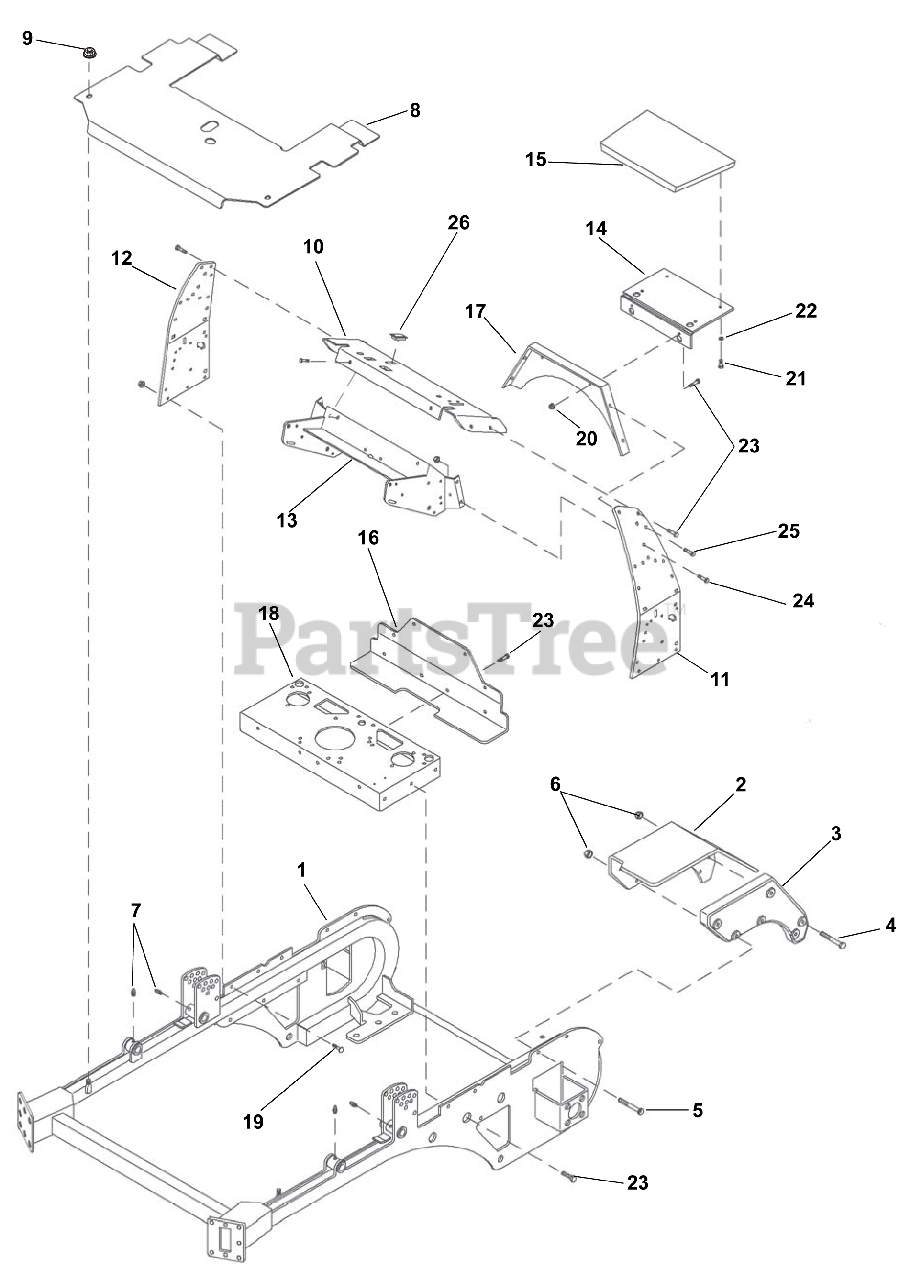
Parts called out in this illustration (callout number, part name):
1	FRAME, W/ 48"-52" DECK
2	FENDER, LEFT
3	WEIGHT
4	BLT-HEX M8-1.25X65 YWZC
5	BLT, HEX M8-1.25X70 YWZC
6	@NUT-LK-NYL M8-1.25 YWZC
7	LUBRICATION FITTING
8	DECK SHIELD ASMBLY, 48"
9	@NUT-LK-TOP-FLG .38-16 YWZC
10	CONTROL CONSOLE
11	SIDE BRACKET, LEFT
12	SIDE BRACKET, RIGHT
13	HANDLE MOUNT
14	PLATE, THIGH PAD
15	PAD, THIGH
16	SHIELD
17	PLATE
18	ENGINE/TRACTION DECK
19	CARRIAGE BOLT, M10 X 1.5 X 25
20	NUT-LK-NYL M10-1.5 YWZC
21	@BLT-HEX .25-20X.75 GR5 YWZC
22	@WSHR-LK .25X.062 REG YWZC
23	BLT-HEX M10 X 1.5X20 GR5 YWZC
24	BLT-HEX M10 X 1.5X25 YWZC
25	@BLT-HEX .38-16X.75 GR5 YWZC
26	3PLUG, EURO STYLE, OPTIONAL LI
